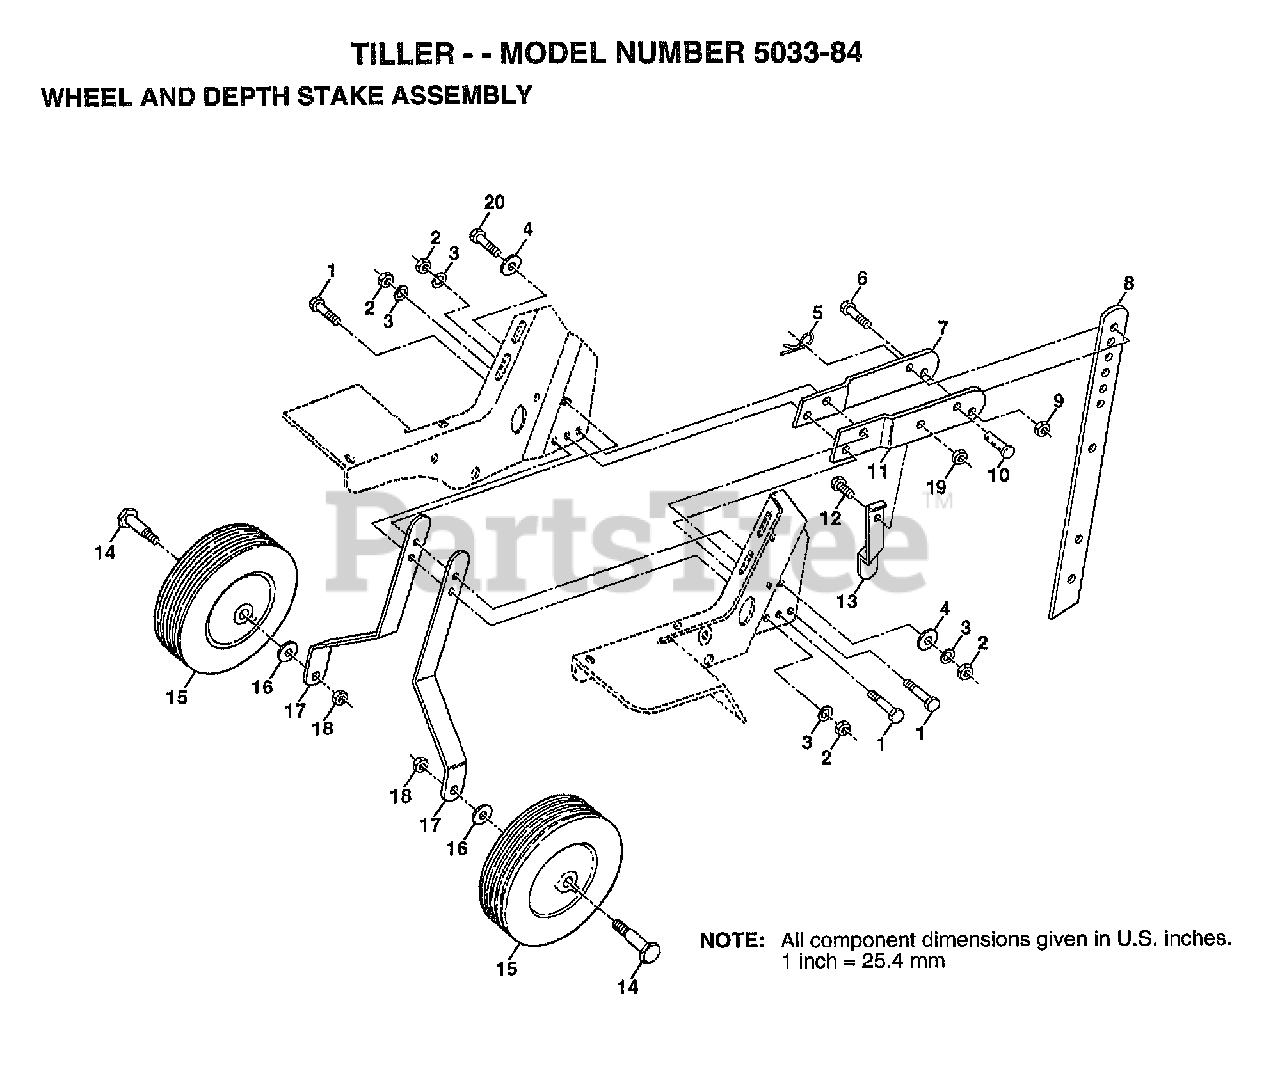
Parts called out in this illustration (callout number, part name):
2	NUT.HEX.5/16-18
3	LOCKWASHER
4	WASHER
5	SPRING.RETAINER
6	BOLT
7	STAKE.SUPT.TILLER
9	NUT
10	DRILLED RIVET RT
12	BOLT
13	STAKE SPRING CT
14	BOLT SHOULDER
16	WASHER
19	NUT
20	BOLT.HEX.5/16-1.5
